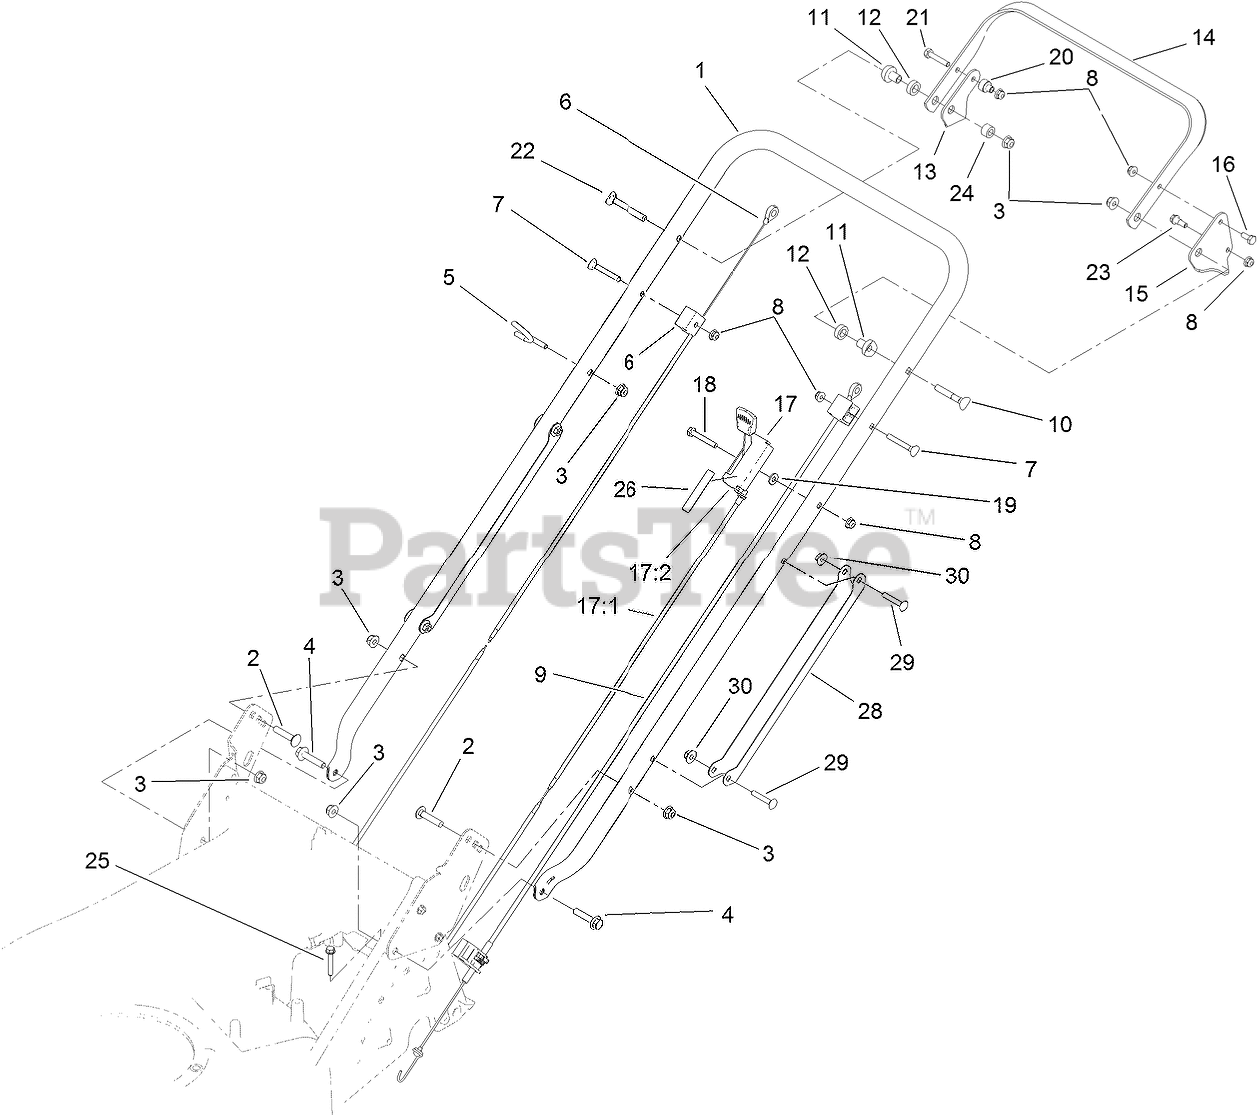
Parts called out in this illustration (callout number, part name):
1	HANDLE
2	BOLT-CARR
3	NUT-HF, NI
4	SCREW-HHF
5	GUIDE,ROPE
6	CABLE-BRAKE
7	SCREW
8	NUT-HF
9	CABLE-TRACTION
10	SCREW-HANDLE
11	SPACER-SUPPORT
12	SPACER-NYLON
13	LEVER-CONTROL, BRAKE
14	BAR-CONTROL, ZONE START
15	LEVER-CONTROL, TRACTION
16	SCREW-HH
17	CONTROL-THROTTLE/CHOKE
17:1	CABLE-THROTTLE
17:2	CONTROL-THROTTLE
18	SCREW-HH
19	WASHER-FLAT
20	SPACER-STEPPED
21	SCREW-HH
22	SCREW-HANDLE
23	BOLT-SHOULDER
24	SPACER
25	SCREW-HWH
26	DECAL-THROTTLE, CHOKE
28	GUARD-CABLE, HANDLE
29	SCREW-CARR
30	NUT-HEX FLG
